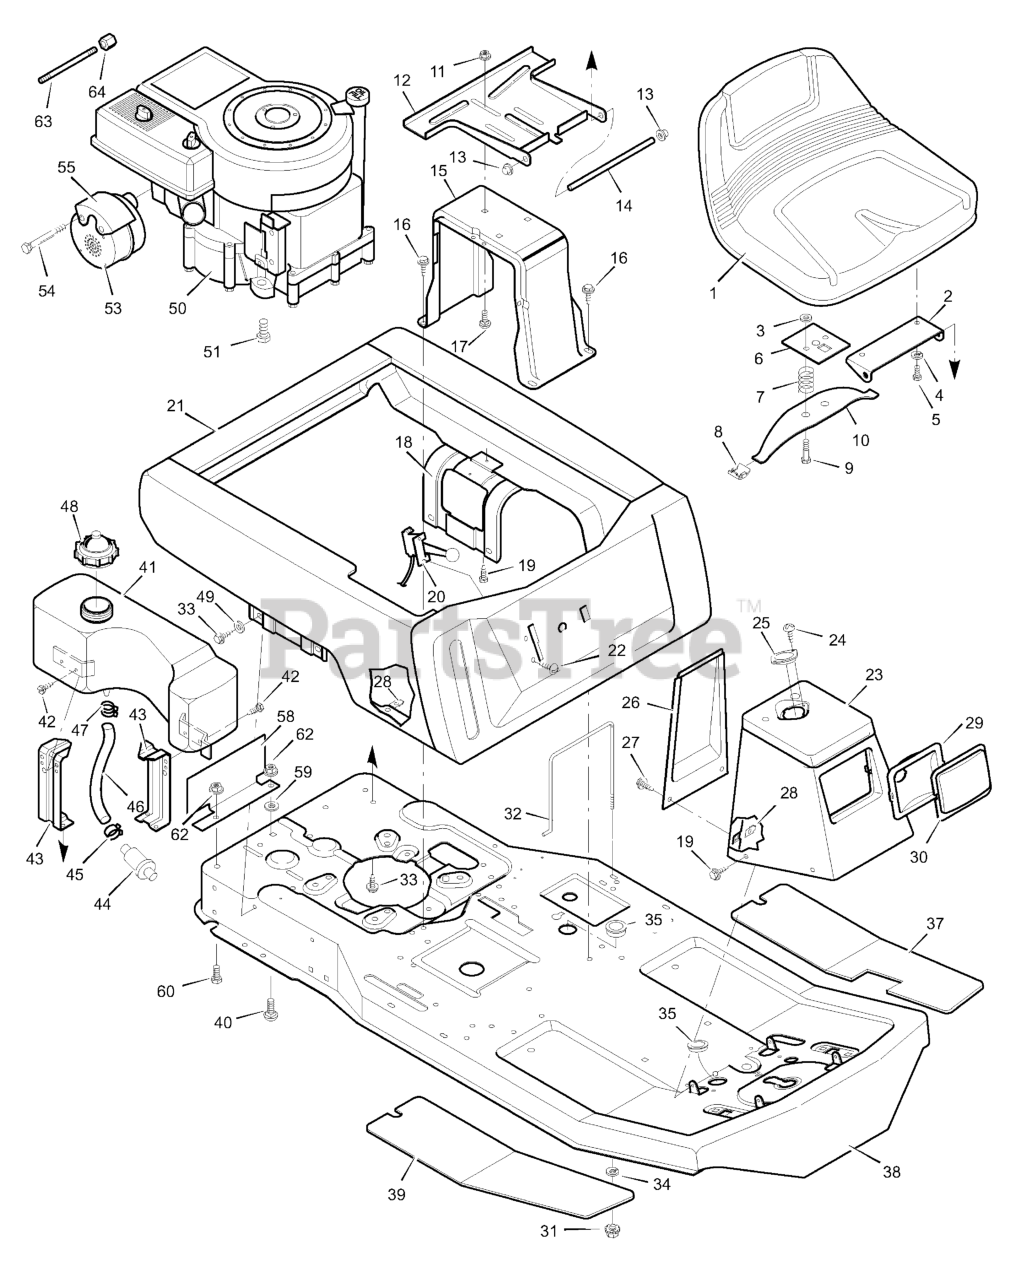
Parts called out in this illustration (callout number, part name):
2	Hinge, Seat
3	Retainer
4	Lockwasher
5	Bolt, Hex
6	Plate, Seat Switch
7	Spring, Compression
8	Glide, Seat Spring
9	Bolt, Shoulder
10	Spring, Seat
11	Locknut, Flange
12	Bracket, Seat Pivot
13	Cap, Push On
14	Rod, Seat Hinge
15	Support, Seat
17	Bolt, Carriage
18	Support, Body
20	Throttle Control
23	Console Assembly
25	Bearing, Steering Post
26	Console, Plate
29	Reflector
31	Locknut
32	Clamp, Battery
35	Grommet
37	Mat, Left
38	Frame Assembly
39	Mat, Right
40	Bolt, Carriage
41	Tank, Fuel
43	Bracket, Fuel Tank
44	Filter, Fuel
46	Line, Fuel
47	Clamp
48	Cap, Fuel
49	Washer
50	Engine *
51	Bolt, Engine Mount
53	Muffler
55	Shield, Heat
59	Washer
60	Bolt
62	Locknut, Flange
63	Pipe, Oil Drain
64	Cap, Oil Drain
